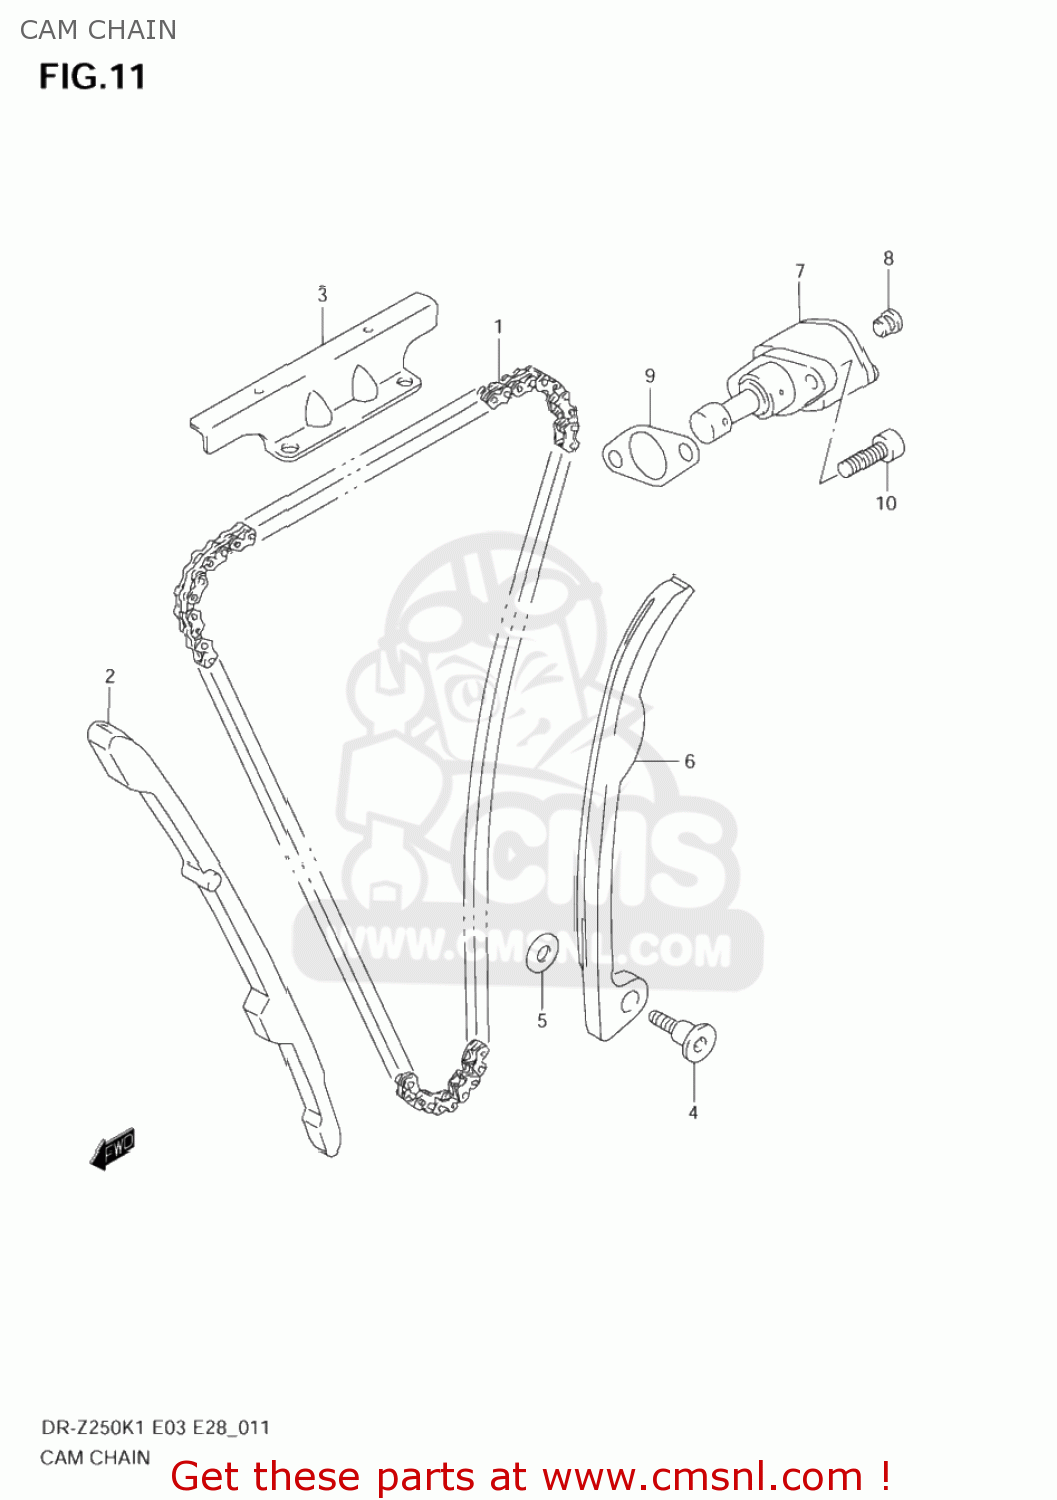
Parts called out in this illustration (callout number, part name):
1	CHAIN,CAMSHAFT DRIVE
2	GUIDE,CAM CHAIN NO.1
3	GUIDE,CAM CHAIN NO.2
4	BOLT,CAM CHAIN TENSIONER
5	WASHER
6	TENSIONER,CAM CHAIN
7	ADJUSTER ASSY,TENSIONER
8	PLUG,ADJUSTER
9	GASKET,TENSIONER ADJUSTER (NAS)
10	BOLT,CRKCASE,R
